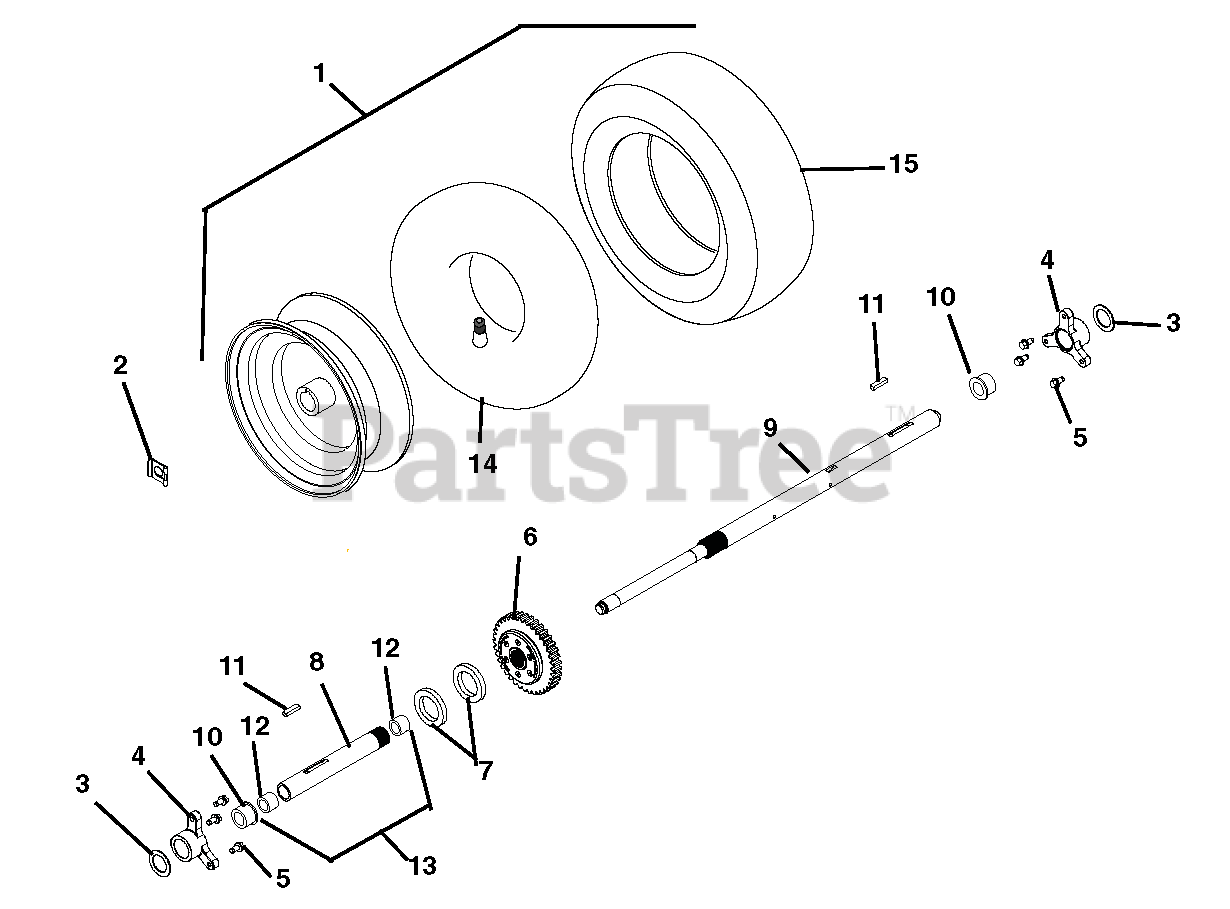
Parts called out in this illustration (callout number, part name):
1	TIRE/WHEEL,RH 16X4.8-8 DIFF T2
1	TIRE/WHEEL,LH 16X4.8-8 DIFF T2
1	TIRE/WHEEL, RH 16X6.50-8 DIFF
1	TIRE/WHEEL, LH 16X6.50-8 DIFF
2	CLIP, SNAP .625 DIA
3	WSHR-FL-STL 1.010X1.505X.062YZ
4	BUSHING, RAKE SHAFT 1"
5	SCR-TAP .25-20X.50 HWH TR YWZ
6	DIFFERENTIAL, AUTOMATIC
7	WSHR-FL-STL- 1.062X2.0X.134 YZ
8	AXLE, SHORT-PRO AUTO DIFF
9	AXLE, LONG-PRO AUTO DIFF
10	BSHG-FLG SPLIT NYLINER 1.0" HP
11	KEY-RECT .25X.188X1.00
12	BSHG-SLV .706X.764X.75 BRZ
13	AXLE, SHORT-AUTO W/BUSHINGS
14	TUBE
15	TIRE, 4.80-8 K478
15	TIRE, 16X6.50-8 K478
